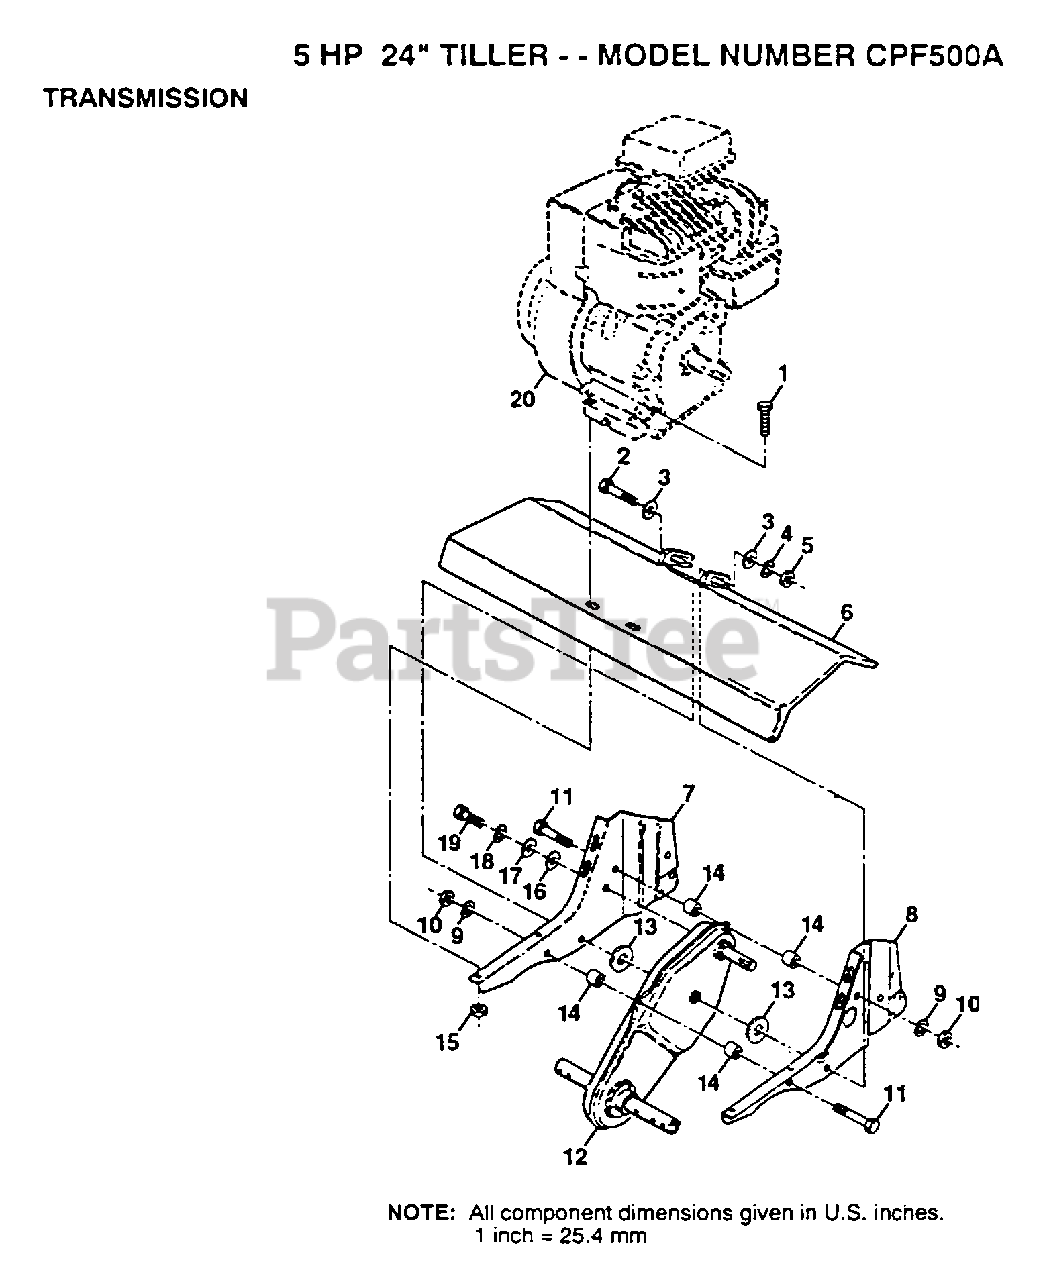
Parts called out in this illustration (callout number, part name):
1	BOLT.HEX.5/16-1.5
2	BOLT.3/8-24X3.75
3	WASHER
4	LOCKWASHER
5	GRIPCO NUT
8	BRACKET.ENG.LH.
9	LOCKWASHER
10	NUT.HEX.5/16-18
14	SPLIT SPACER RT
16	WASHER
17	WASHER
18	LOCKWASHER
19	BOLT
